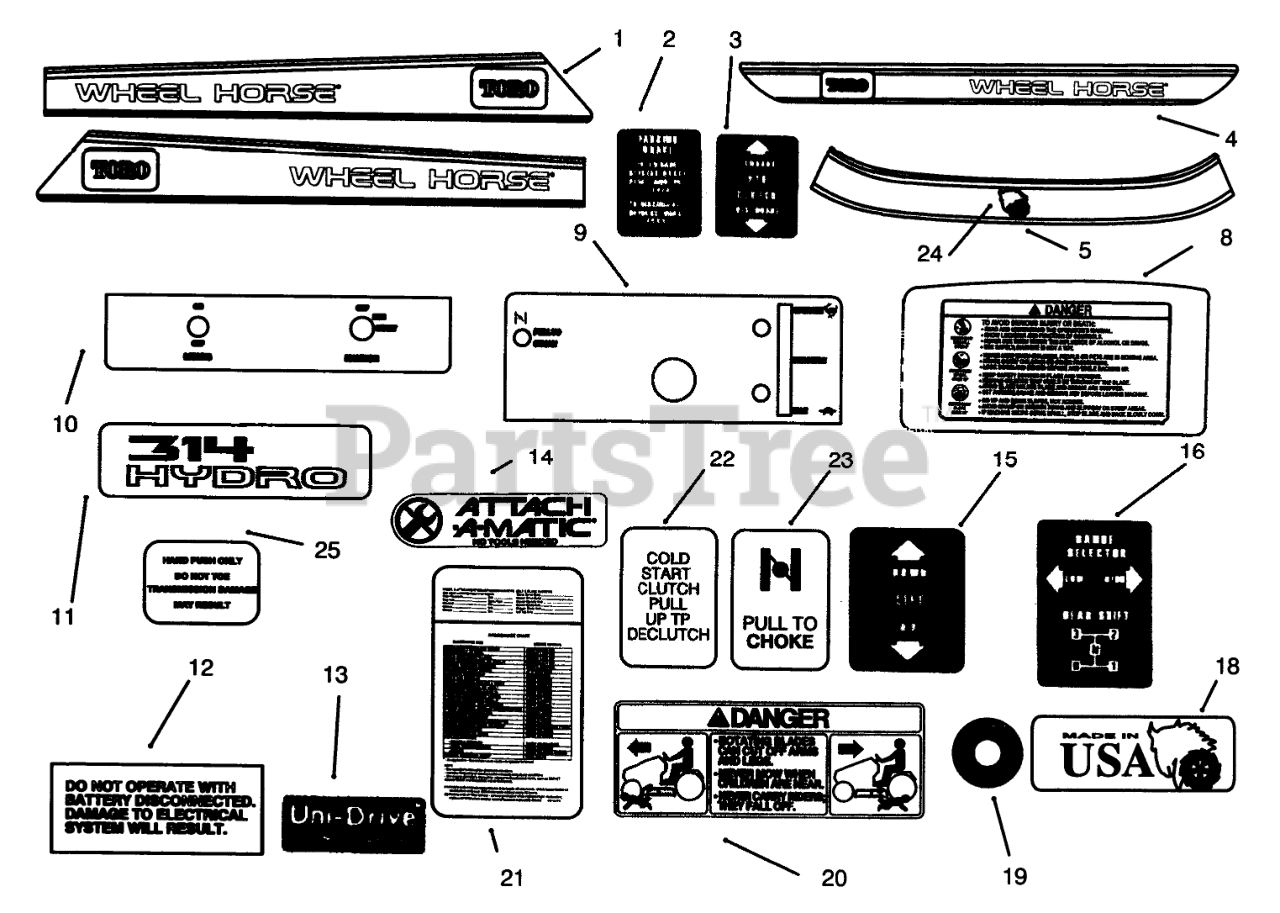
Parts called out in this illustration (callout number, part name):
1	DECAL - RH HOOD TOP
2	DECAL-PARKING BRAKE
3	DECAL PTO CLUTCH
4	DECAL - REAR FENDER
5	DECAL-FRONT HOOD, TOP
8	DECAL - DANGER
9	DECAL-DASH
10	DECAL-BACK PLATE
11	DECAL - MODEL 314-H
12	DECAL ELECT SYSTEM
13	Decal-Unidrive
14	DECAL-ATTACH A-MATIC
15	DECAL-LIFT
16	DECAL-SHIFT PATTERN
18	DECAL - USA
19	Decal-Air Cleaner
20	DECAL-DANGER
21	Decal-Maintenance
22	DECAL-COLD START
23	DECAL-CHOKE
24	PLATE - LOGO WHL HORSE
25	DECAL-DO NOT TOW
